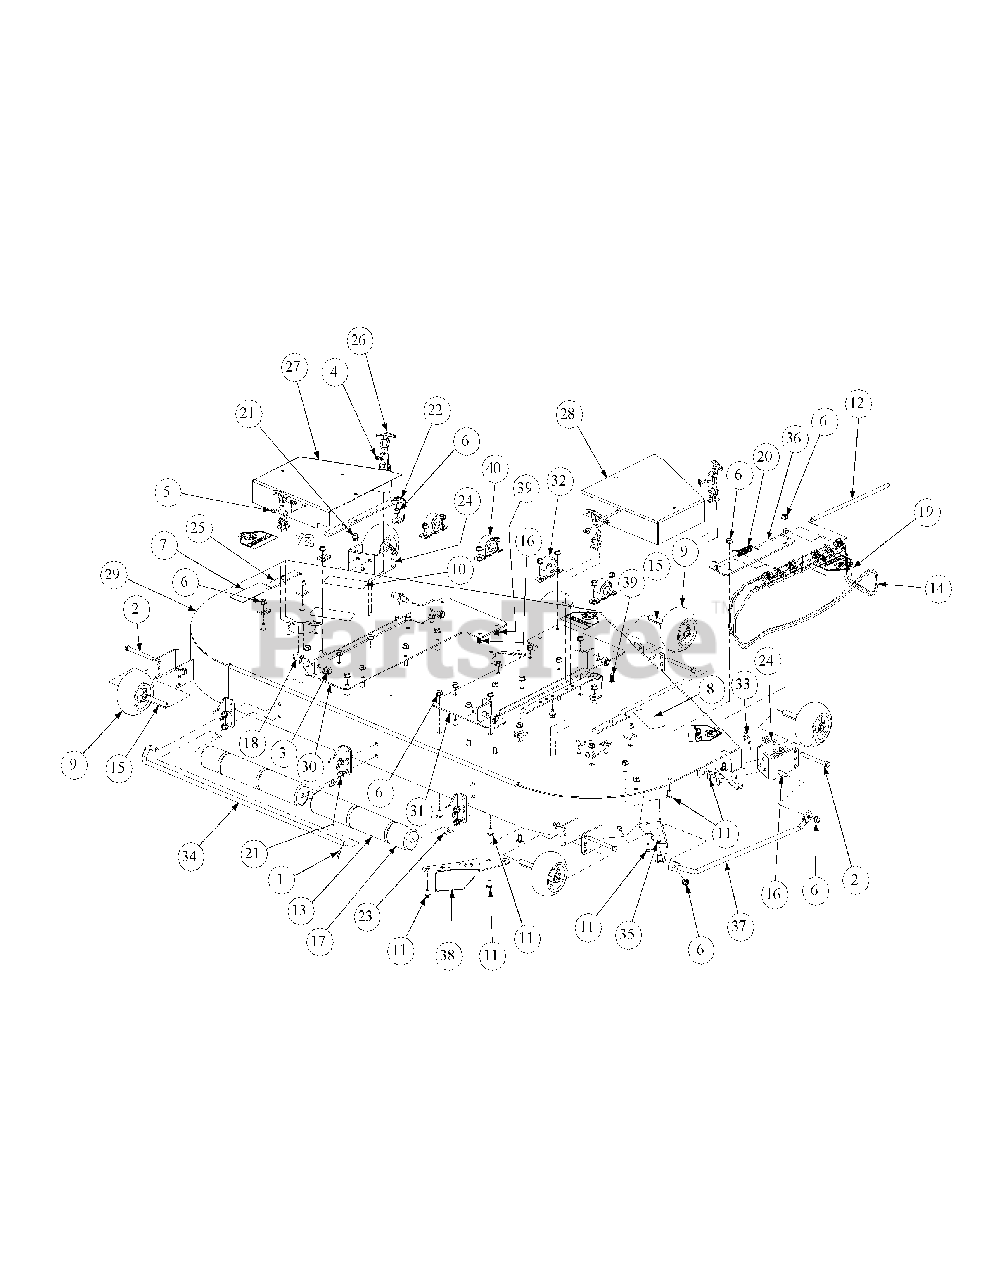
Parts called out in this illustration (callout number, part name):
1	Cotter Pin, .125 Dia. x 1.0
2	Hex Cap Screw, 3/8-16, 3.75
3	Lock Nut, Nylon Insert, 1/2-13
4	Lock Nut, Nylon Insert, #10-32
5	Phillips Head Screw, #10-32 x 1/2
6	Flange Lock Hex Nut, 3/8-16
7	Decal, Rotating Blade
8	Decal, Warning Shield Missing
9	Complete Wheel, 5.00 Dia.
10	Command Cut Large
11	Carriage Bolt, 3/8-16 x .75 Lg.
12	Pin, .375 x 14.06
13	Front Roller
14	Chute Deflector
15	Wheel Spacer
16	Carriage Bolt, 3/8-16 x 1
17	Grass Catcher Roller
18	Pin, 5/8 Dia. x 1.2 Lg.
19	Decal, Danger Hand and Feet
20	Torsion Spring, 0.4ID x 2.16Lg
21	Hex Index Washer Screw, 3/8-16, .5
22	Belt Cover Support
23	Deck Roller Mount Bracket
24	Anti-Scalp Wheel Front Mount Bracket
25	Outer Belt Cover Support Assembly
26	T-Handle Latch Draw
27	Left Hand Deck Belt Cover Weldment
28	Right Hand Deck Belt Cover Weldment
29	72" Deck Assembly
30	Left Hand Deck Weldment Bracket
31	Right Hand Deck Weldment Bracket
32	Pillow Block, Steel
33	Decal, 72"
34	Roller Pin
35	Chute Bracket
36	Chute Bracket
37	Finger Guard
38	Discharge Baffle Weldment
39	Carriage Screw, 3/8-16 x 1.25
40	Pillow Block, Bronze
